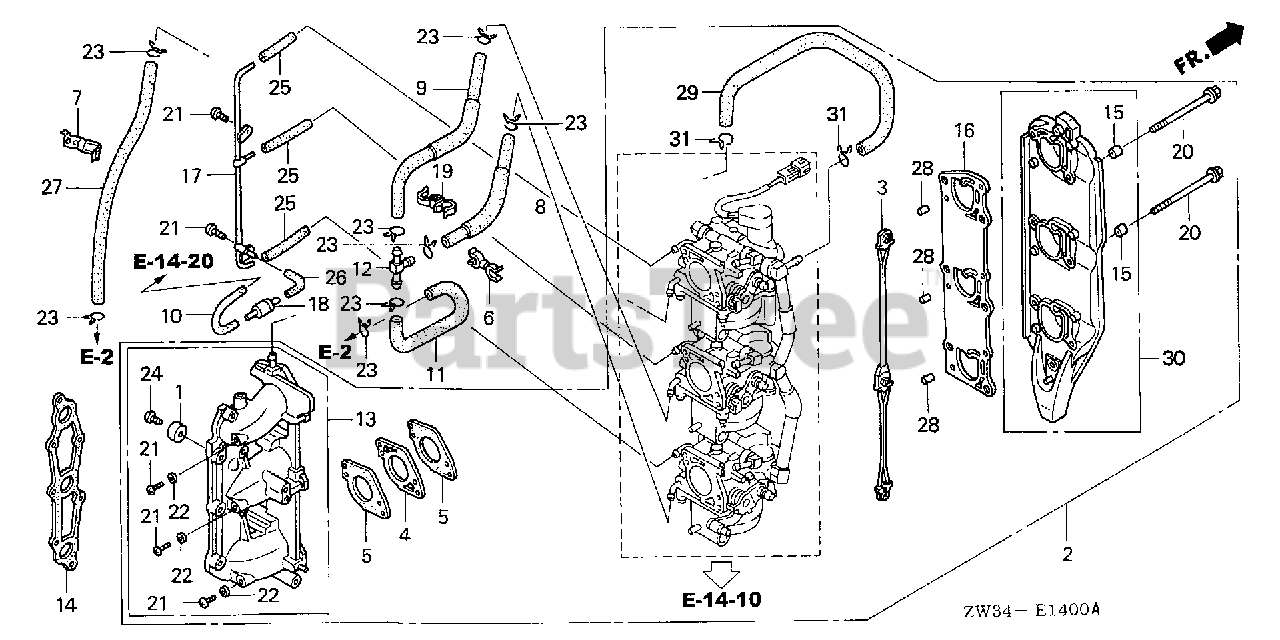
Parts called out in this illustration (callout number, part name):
1	METAL, ANODE
2	CARBURETOR ASSY. (BG30D D) *NH8* (DARK GRAY)
3	LEVER, LINK
4	INSULATOR, CARBURETOR
5	GASKET, CARBURETOR
6	CLAMP, FUEL TUBE (A)
7	CLAMP, FUEL TUBE
8	TUBE C, FUEL
9	TUBE F, FUEL
10	TUBE D, FUEL
11	TUBE E, FUEL
12	PIPE, THREE WAY JOINT
13	MANIFOLD ASSY., IN. *NH8* (DARK GRAY)
14	GASKET, IN. MANIFOLD
15	COLLAR, DISTANCE
16	GASKET, MUFFLER PLATE (CARBURETOR NO.)
17	PIPE, INSTALL
18	VALVE, DASHPOT CHECK
19	CLIP, R. BRAKE WIRE
20	BOLT, FLANGE (6X97)
21	SCREW, PAN (5X10)
22	WASHER, SEALING (5MM)
23	CLIP, TUBE (B10)
24	SCREW, PAN (6X18)
25	BULK HOSE, FUEL (3.5X3000) (3.5X45)
26	BULK HOSE, FUEL (3.5X3000) (3.5X60)
27	BULK HOSE, FUEL (5.5X3000) (5.3X240)
28	ROLLER (6X15)
29	TUBE, BYSTARTER
30	PLATE, MUFFLER (CARBURETOR NO.)
31	CLIP, TUBE (B10)
